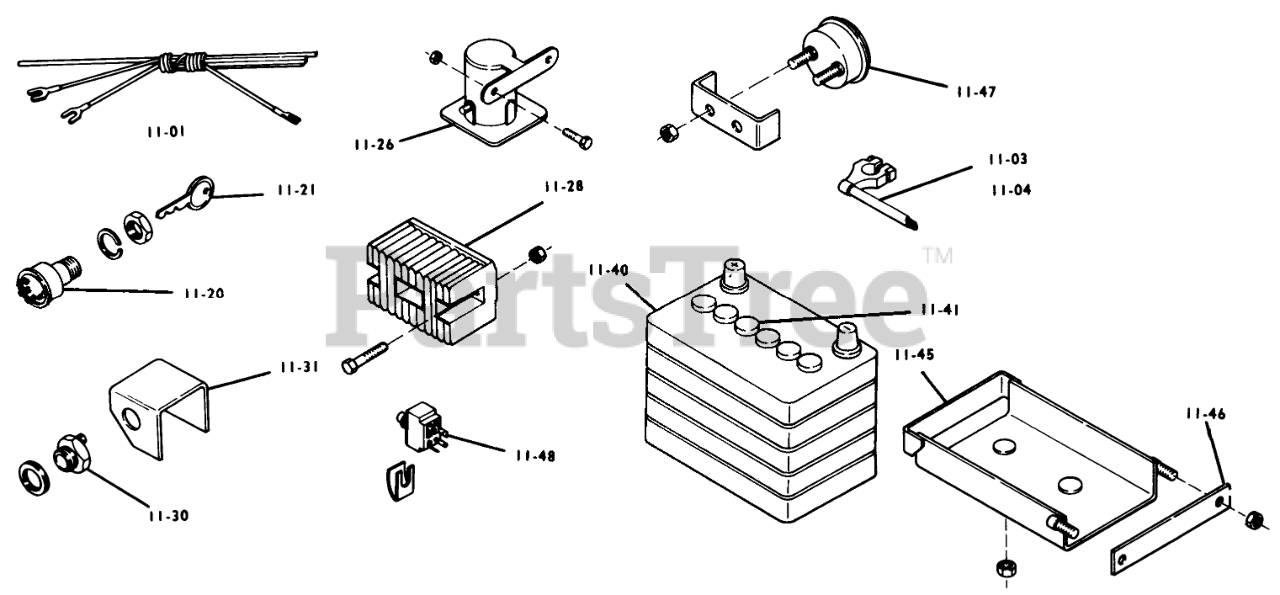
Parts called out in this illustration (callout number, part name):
11-01	WIRING HARNESS & DIA
11-02	Grommet
11-03	Wire-Ground
11-04	WIRE SOLENOID
11-05	Wire
11-06	WIRE ASSY
11-07	Wire Assy.
11-10	ASSY FUSED CONNECTOR
11-14	Wire Harness-Lights
11-20	SWITCH-IGNITION
11-21	Key-EL
11-24	SWITCH-LIGHTS
11-25	AMMETER W/CLAMP
11-26	Solenoid
11-28	REGULATOR-RECTIFIER
11-30	SWITCH SAFETY
11-30A	SWITCH-CLUTCH
11-31	Bracket
11-40	BATTERY
11-42	Cover Battery Term
11-45	BATTERY BOX ASSY R (NS)
11-46	LINK BATTERY CLAMP
11-47	AMMETER W/CLAMP
11-48	SWITCH-CLUTCH
